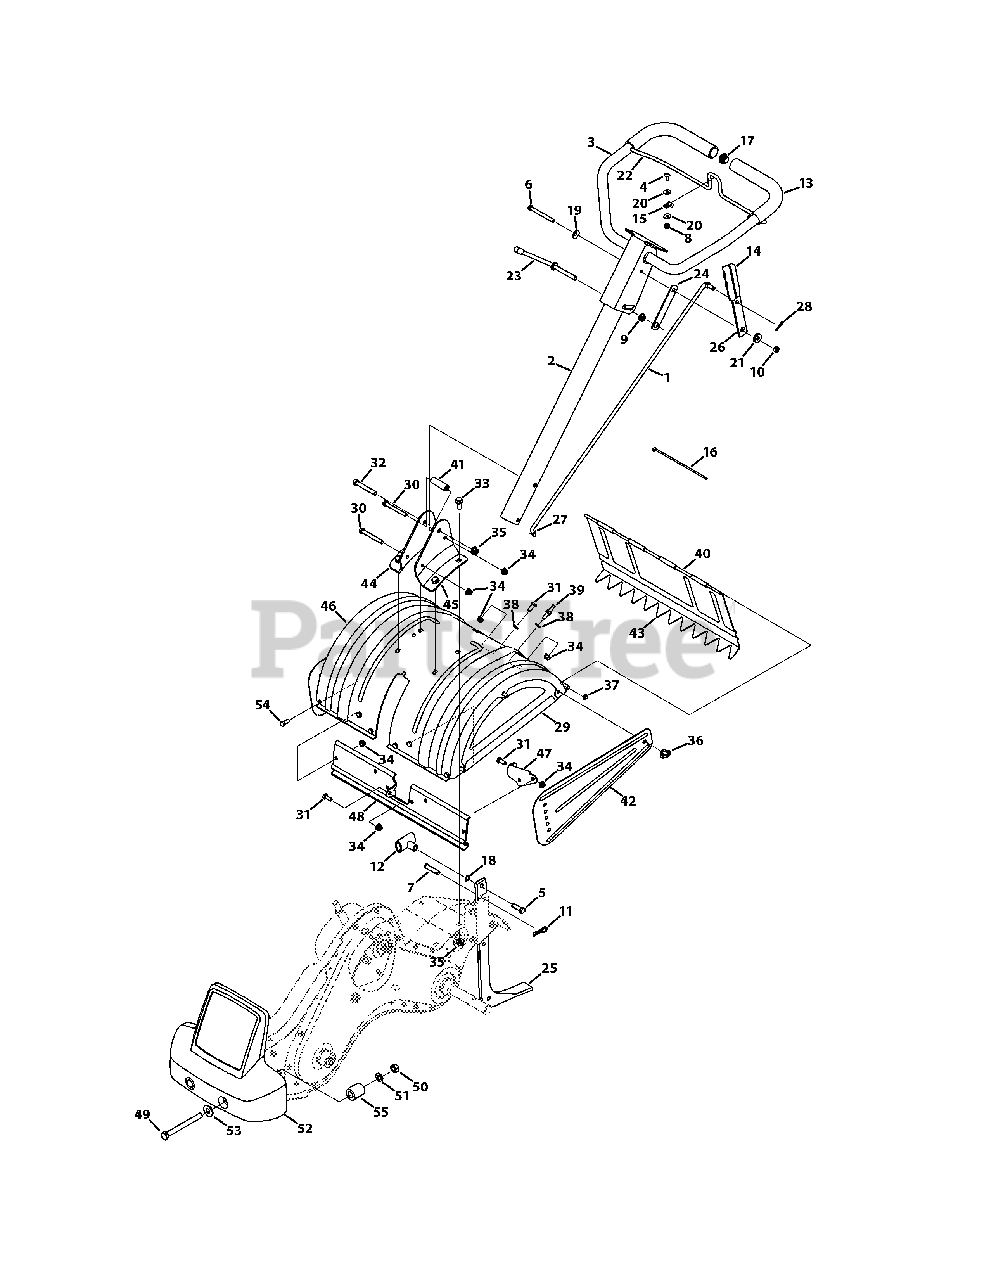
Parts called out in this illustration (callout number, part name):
1	Shaft Rod
2	Lower Handle Tube Assembly
3	Upper Handle Assembly
4	Screw, 1/4-20 x 0.625
5	Hex Head Screw, 3/8-16:1.25
6	Hex Head Screw, 5/16-18 x 3.25
7	Clevis Pin, .375 X 1.75
8	Hexlock Nut, 1/4-20
9	Flangelock Nut, 3/8-24
10	Hexlock Nut, 5/16-18
11	Cotter Pin, .125 X 1.75 INTERNAL
12	Small Tee Knob
13	Foam Grip, .970 x 11.0
14	Grip, .1875 x 1.00
15	Battery Clamp, 5/16
16	Cable Tie, 8.5 LG
17	End Plug
18	Washer, Flat, .385 x .620 x .033
19	Washer, Bell, .340 x .872 x .060
20	Washer, Flat, .260 x .720 x .060
21	Spacer, Shoulder, .50 x .190 x .360 LG
22	Clutch Bail
23	Handle Adjustment Crank
24	Hex Nut Retainer Bracket
25	Tiller Depth Control
26	Shaft Rod Lever
27	Washer, Rubber, .33 ID x .87 OD x .125
28	Cotter Pin, .072 x 1.12 LG
29	End Cover Assembly
30	Hex Head Screw, 5/16-18 x 2.75
31	Hex Head Screw, 5/16-18 x .75
32	Hex Head Screw, 3/8-16 x 2.75
33	Hex Head Flange, 3/8-16 x .875
34	Flangelock Nut, 5/16-18
35	Flangelock Nut, 3/8-16
36	Wing Nut, 5/16-18 W/ Bell Washer
37	Speed Nut Cap, 1/4 ROD
38	Washer, Flat, .344 x .62 x .033
39	Screw, Hex, 5/16-18 x .75
40	Tiller Flap Rod
41	Spacer, .322 x .625 x 2.00
42	Side Shield
43	Rear Tine Shield
44	RH Handle Mount Bracket
45	LH Handle Mount Bracket
46	Tine Shield
47	FRT Tine Shield Bracket
48	FRT Tine Shield Spacer Bracket
49	Hex Head Screw, 1/2-13 x 5.00
49	Hex Head Screw, 1/2-13 x 5.50
50	Hex Nut, 1/2-13
50	Hex Nut, 1/2-20
51	Washer, Lock, 1/2
52	Counterweight
53	Washer, Flat, 1/2 x 1.25 x .100
54	Hex Head Screw, 5/16-18 x 1.00
55	Hub, .636 ID x 1.00 OD x .94
